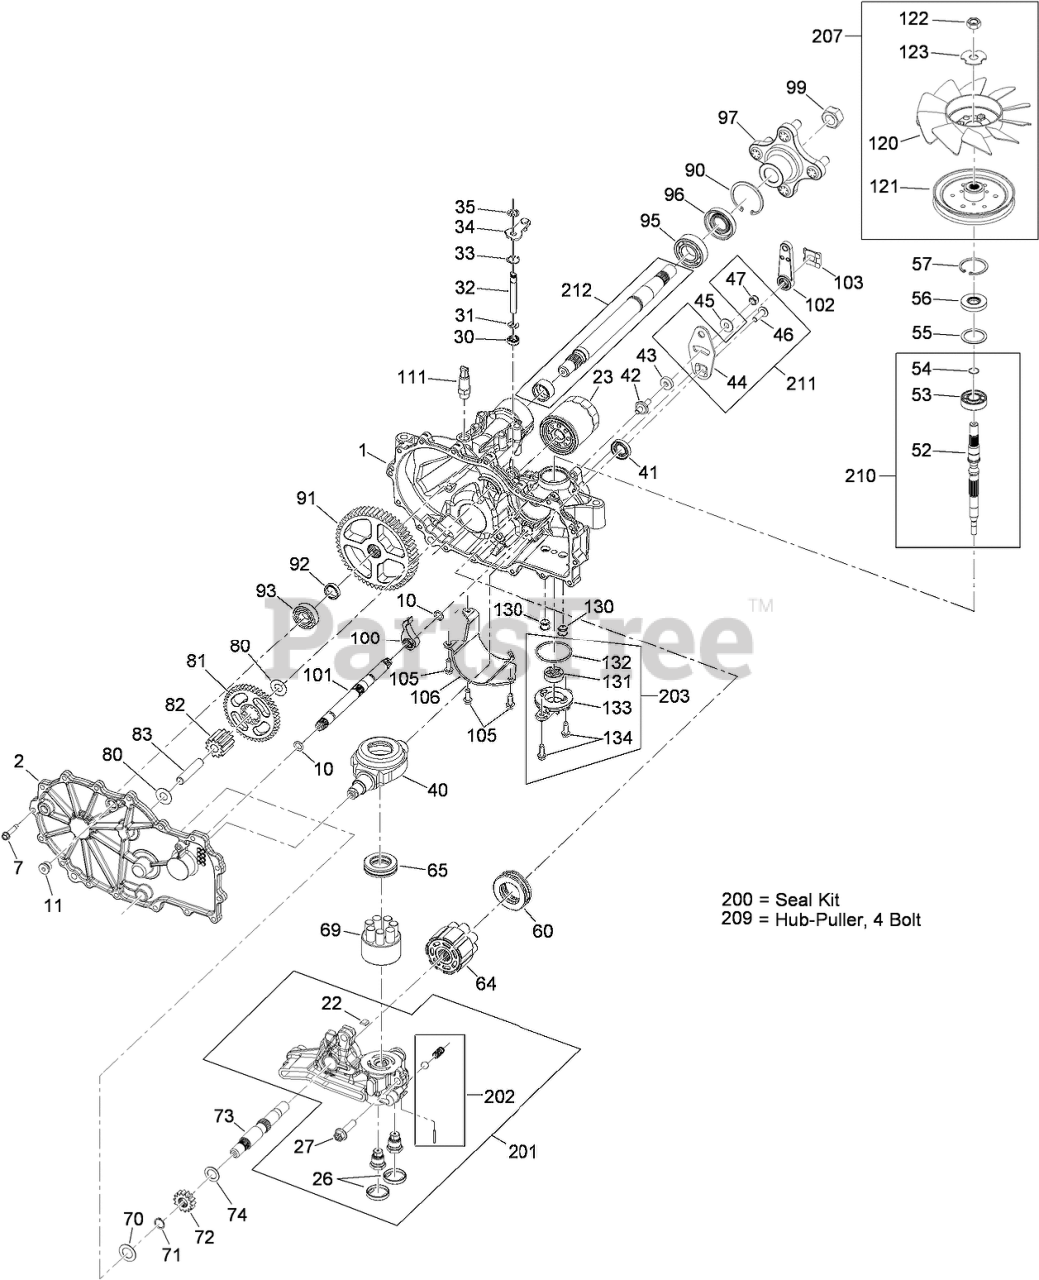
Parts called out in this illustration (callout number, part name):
1	LH MAIN HOUSING KIT
2	LH SIDE COVER KIT
7	SCREW-HHF
10	O-RING
11	PLUG-THREAD, STRAIGHT
22	PLATE-BYPASS
23	ELEMENT-OIL FILTER, HYD
26	SEAL-PLUG
27	SCREW-HFHC
30	SEAL-LIP
31	RING-RETAINING, EXTERNAL
32	ROD-BYPASS
33	RING-RETAINING, INTERNAL
34	ARM-BYPASS
35	RING-RETAINING, EXTERNAL
40	SWASHPLATE-TRUNNION
41	SEAL-LIP
43	PUCK-FRICTION
44	ARM-CONTROL
45	WASHER
52	SHAFT-INPUT
53	BEARING-BALL
54	RING-RETAINING
55	SPACER
56	SEAL-LIP
57	RING-RETAINING
60	BEARING-THRUST
64	MOTOR CYLINDER BLOCK KIT
65	BEARING-THRUST
69	PUMP BLOCK ASM
70	WASHER-FLAT
71	RING-RETAINING
72	GEAR-14T
73	SHAFT-MOTOR
74	WASHER
80	WASHER
81	GEAR-45T
82	GEAR-11T
83	PIN-JACKSHAFT
90	RING-RETAINING
91	GEAR-54T
92	SPACER
93	BEARING-BALL
95	BEARING-BALL
97	HUB KIT
99	NUT-HUB
100	PAWL-BRAKE
101	SHAFT-BRAKE
102	HANDLE-BRAKE
103	CLIP-RETAINING
106	GUARD-FILTER, LH
111	ADAPTER-STRAIGHT
120	FAN-7.0
121	PULLEY-5.0 INCH
122	NUT-HEX
123	WASHER-SLOTTED
130	TUBE-CONNECTING
131	GEROTOR ASM
132	O RING-SEAL
133	COVER-CHARGE PUMP
200	SEAL KIT
201	LH CENTER SECTION KIT
202	CHARGE RELIEF KIT
203	CHARGE KIT
207	FAN AND PULLEY KIT
209	PULLER-HUB, 4 BOLT
210	INPUT SHAFT KIT
211	CONTROL ARM KIT
212	AXLE SHAFT KIT
